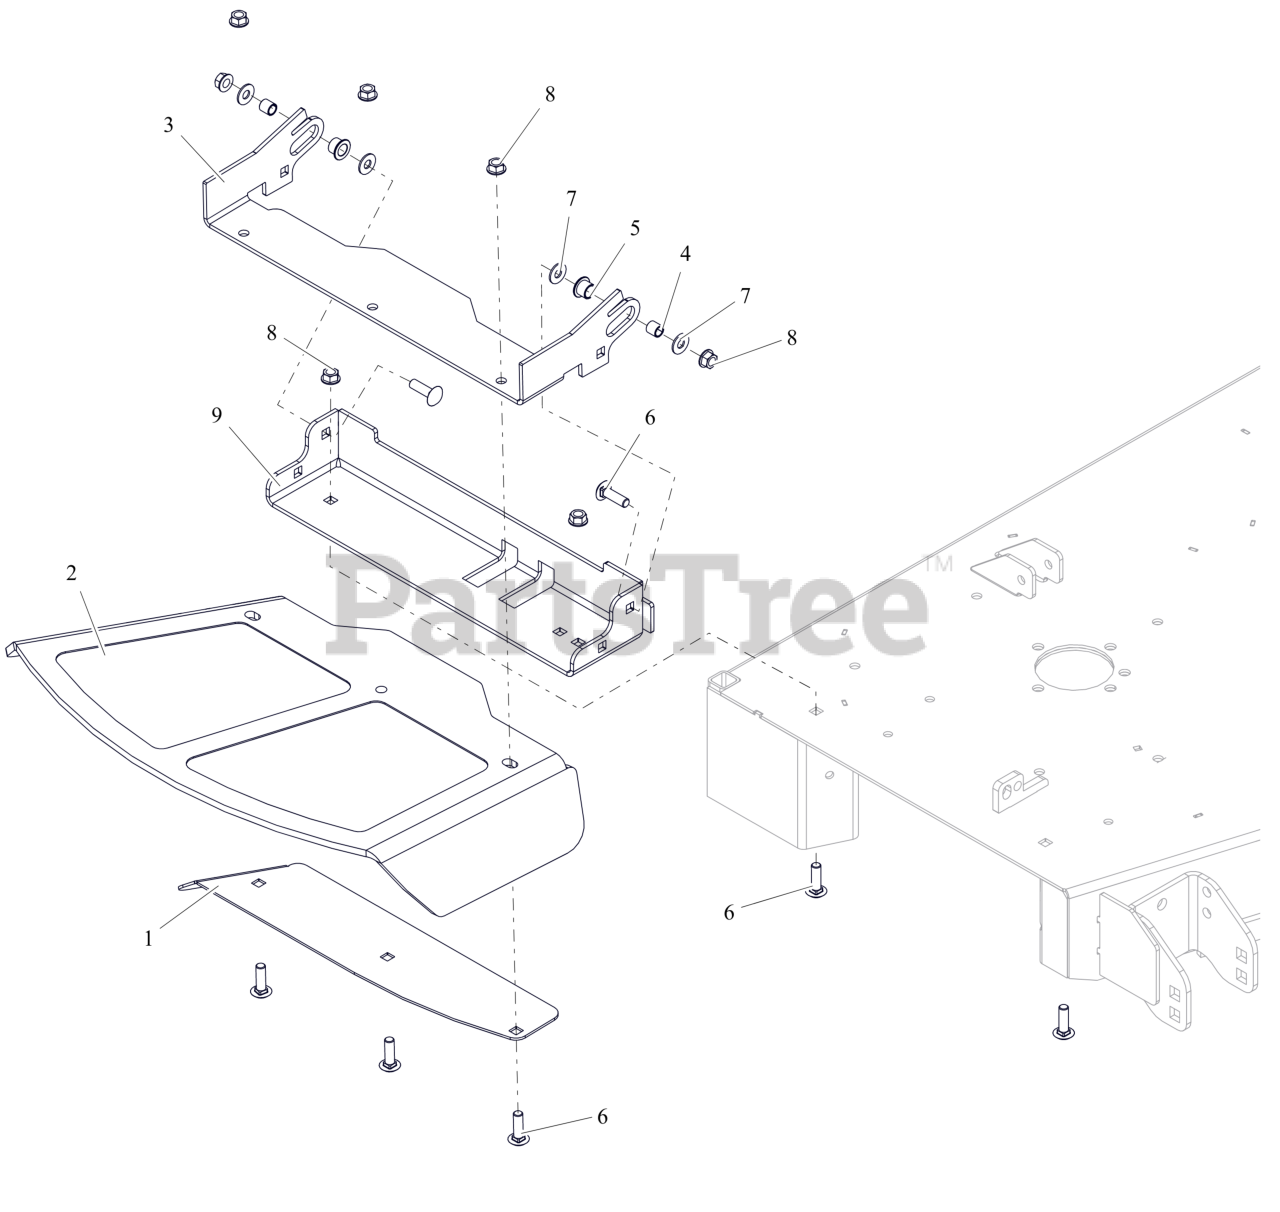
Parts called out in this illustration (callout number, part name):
1	48-60 DISCH CHUTE CLMP PLT-ORG
2	CHUTE, FORMED RUBBER DISCHARGE
3	BRKT, CHUTE MOUNT (ORANGE)
4	SPCR, .385X.500X.350
5	BSHG, FLANGED .50X.625X.50X.062
6	BLT,RHSSN .38-16X1.25 G5 ZCC
7	WSHR, HDND .375X.875X.064 ZCC
8	NUT-LK-CTR-FLG .375-16 GF ZCC
9	BASE, DISCHARGE CHUTE MTG BRKT (ORANGE)
